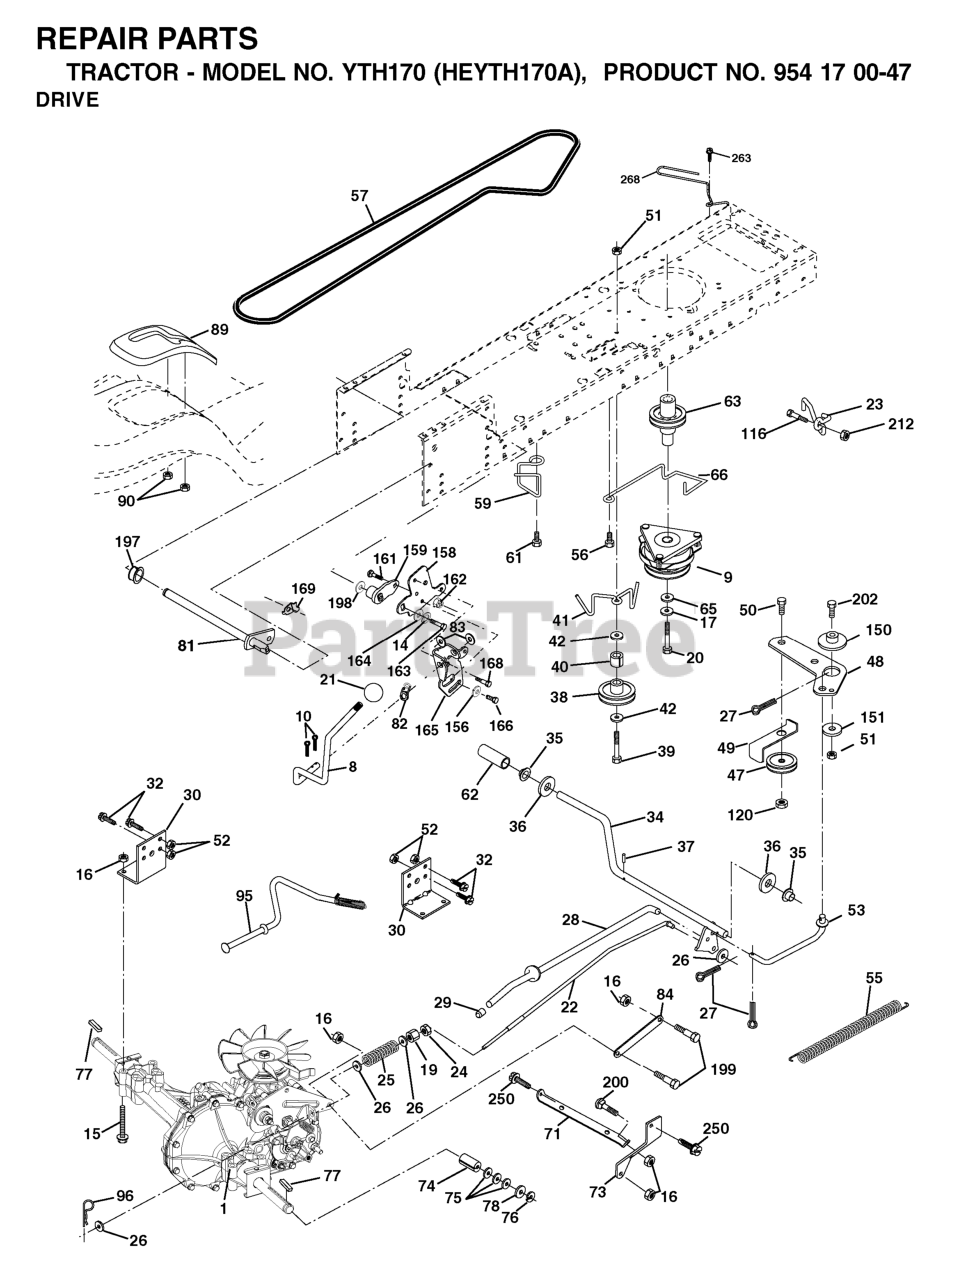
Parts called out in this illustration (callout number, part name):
8	ROD SHIFT FENDER ADJUST STLT
10	PIN COTTER
14	LOCKWASHER
15	BOLT HEX 5/16-18 GR 5
16	NUT.71038.31-18.HEX.NYLOCK
19	NUT
20	BOLT HEX 7/16-20X4-1/4"
21	KNOB.DUCKHEAD.1/2
22	ROD BRAKE HYDRO
23	BRKT ASM MTNG
24	NUT
25	SPRING ROD LT
26	WASHER
27	COTTER PIN
28	ROD, PARKING BRAKE
29	PLUNGER CAP
30	BRKT, TRNSXLE MNT 20"
32	BOLT
34	SHAFT, FOOT PEDAL
35	BEARING.NYLON
37	DRIVE PIN
38	PULLEY IDLER COMPOSITE
39	BOLT
41	KEEPER, BELT IDLER
47	IDLER PULLEY
48	BELLCRANK, CLUTCH
49	RETAIN BELT
50	BOLT
52	LOCKNUT
53	LINK, CLUTCH LT
55	SPRING, RETURN LT
56	SCREW.3/8-16
57	DRIVE BELT, LTH & YTH TRACTORS
59	KEEPER, BELT CENTER
61	SCREW 3/8-16X.875
62	COVER, PEDAL (1 2)
63	PULLEY- ENGINE
65	LOCKWASHER
66	KEEPER BELT ENGINE
71	STRAP TORQUE LH HYDRO
73	STRAP TORQUE RH HYDRO
74	SPACER AXLE
77	SQUARE KEY
81	SHAFT ASM CROSS TAPERED
82	SHIFT SPRING
83	WASHER
84	LINK TRANSAXLE
89	SHIFT CONSOLE
90	NUT.PUSH.3/16
95	CONTROL ASM. BYPASS HYDRO
96	RETAINER M
116	BOLT D
120	NUT LOCK FLG 3/8-16 UNC
150	SPACER, RETAINER
151	WASHER 12/32X2X10GA
156	WASHER.SRRTD.5/16
158	BRACKET
159	HUB
161	BOLT
162	NUT.CROWNLOCK.1/4
164	Washer 5/8 x .281 x 10 Ga.
165	RP BRACKET
168	BOLT.SHOULDER.5/16-18X
169	PLATE.FASTENING.CROSS.SHAFT
197	NYLINER SNAP 5/8" ID
198	WASHER.NYL.7/8IDX.105"HYD CR
199	BOLT SHOULDER 5/16-18 UNC
212	NUT
250	SCREW 3/8-16X3/4
263	SCREW, 3/8-16X3/4
268	GUARD MUFFLER
